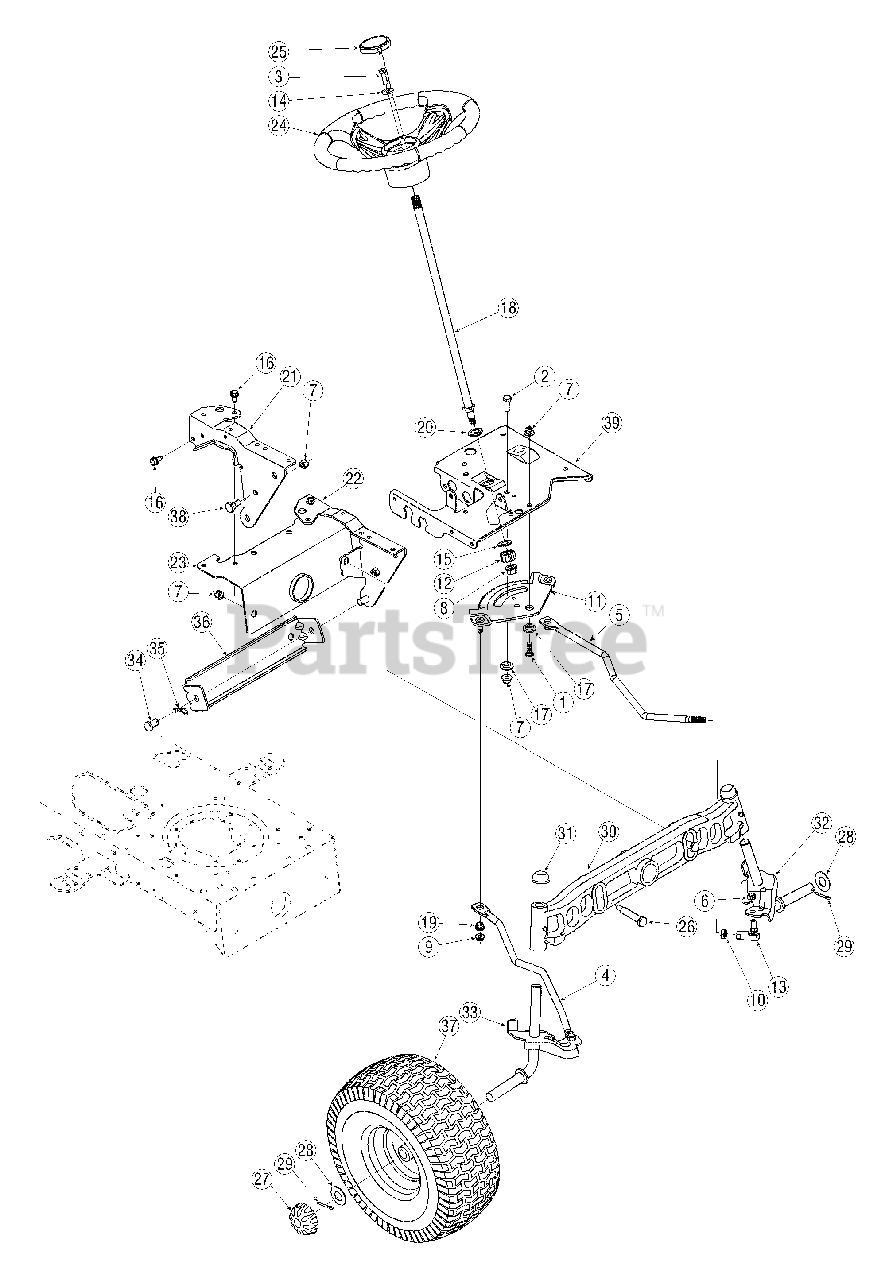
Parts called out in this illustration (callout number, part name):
1	Hex Screw, 3/8-16, 1.00, Gr5
2	Hex Screw, 3/8-16, 1.00, Gr5
3	Hex Screw, 5/16-18, 1.00, Gr5
4	Link, Drag, RH
5	Link, Drag, LH
6	Nut, Hex Lock, 3/8-24
7	Nut, Flange Lock, 3/8-16, Grf, Nylon
8	Nut, Flange Lock, 7/16-20
9	Nut, Flange Lock, 5/16-18, Gr5
10	Nut, Jam, 7/16-20, Gr2
11	Gear, Steering, 11/90 Ratio
12	Gear, Pinion, Steering
13	Ball Joint, 7/16-20, Lock
14	Washer, Flat, .406 x .875 x .105
15	Washer, Flat, .51 x 1.12 x .06
16	Screw, 5/16-12, 0.750
17	Spacer, Shoulder, .38 x 1.00 x .31
18	Shaft, Steering, .625 OD x 24.25 Lg
19	Plastic Bushing .380 ID
20	Hex Flange Bearing 5/8 PM
24	Steering Wheel, 13.25
25	Steering Wheel Cap, Round
26	Shoulder Screw, .5 x 2.2, 3/8-16
27	Deluxe Hub Cap
28	Flat Washer, .78 x 1.589 x .06
29	Cotter Pin, 5/32 x 1.25
30	Cast Iron Pivot Bar
31	Push Cap
32	LH Axle Assembly, .750
33	RH Axle Assembly, .750
34	Pin, Clevis, .50 x .78
35	Cotter Pin, Internal, .080 x 1.5625
38	Screw, Shoulder, .498 x .340, 3/8-16
